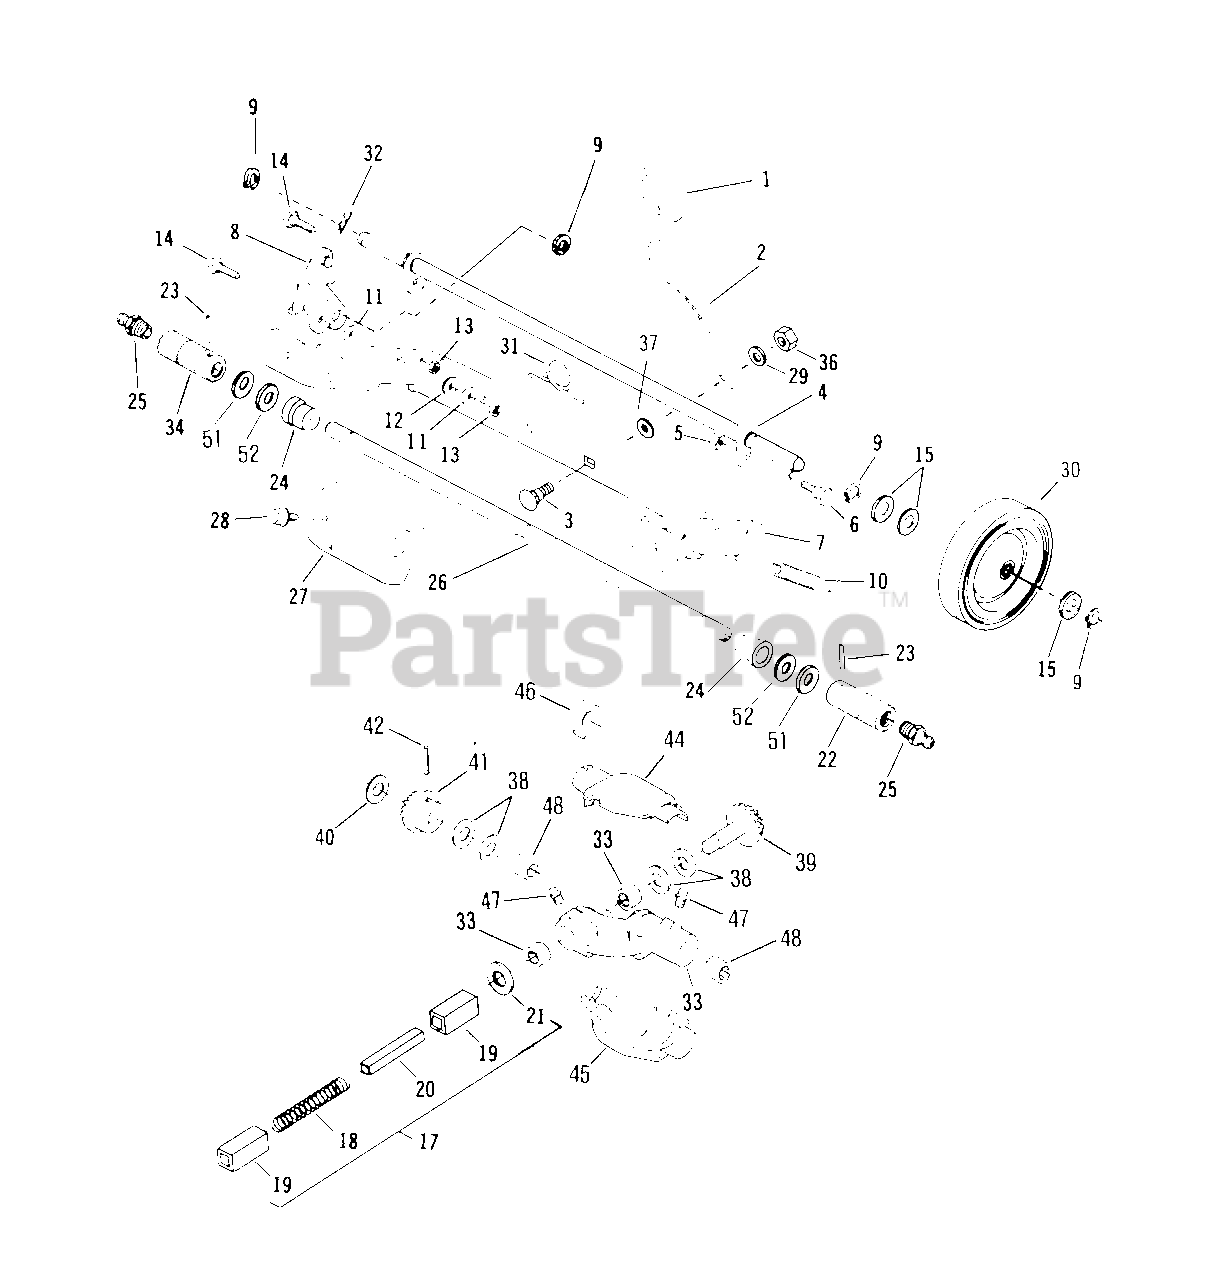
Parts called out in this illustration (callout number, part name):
1	Knob-Rear Height Adjust Lever
2	Lever-Rear Height Adjust
3	Shoulder Bolt-Height Adj. Lever
4	Axle Assembly
5	Locknut
6	Bolt-Shoulder
7	Bracket-21" Axle
8	Clutch Assembly
9	Retaining Ring
10	Spring
11	Washer
12	Lockwasher
13	Stopnut
14	Bolt-Shoulder
15	Washer
16	Washer
17	Driveshaft Assembly
18	Spring-Compression
19	Bushing-Driveshaft
20	Driveshaft
21	Washer
22	Drive Roller-L.H.
23	Pin-Groove
24	Sleeve and Bearing Assembly
25	Grease Fitting
26	Shaft
27	Guard-Roller
28	Screw
29	Washer
30	Wheel-Rear
31	Spring-Height Adjust
32	Lock Pin
33	Bracket and Bearing Assembly
34	Drive Roller-R.H.
35	Spacer
36	Locknut
37	Washer-Height Adjust Lever
38	Washer
39	Gear-Drive
40	Washer
41	Gear Driven
42	Spring Pin
43	Bearing
44	Upper Gear Cover
45	Lower Gear Cover
46	Clamp
47	Zerk Fitting
48	Bearing
